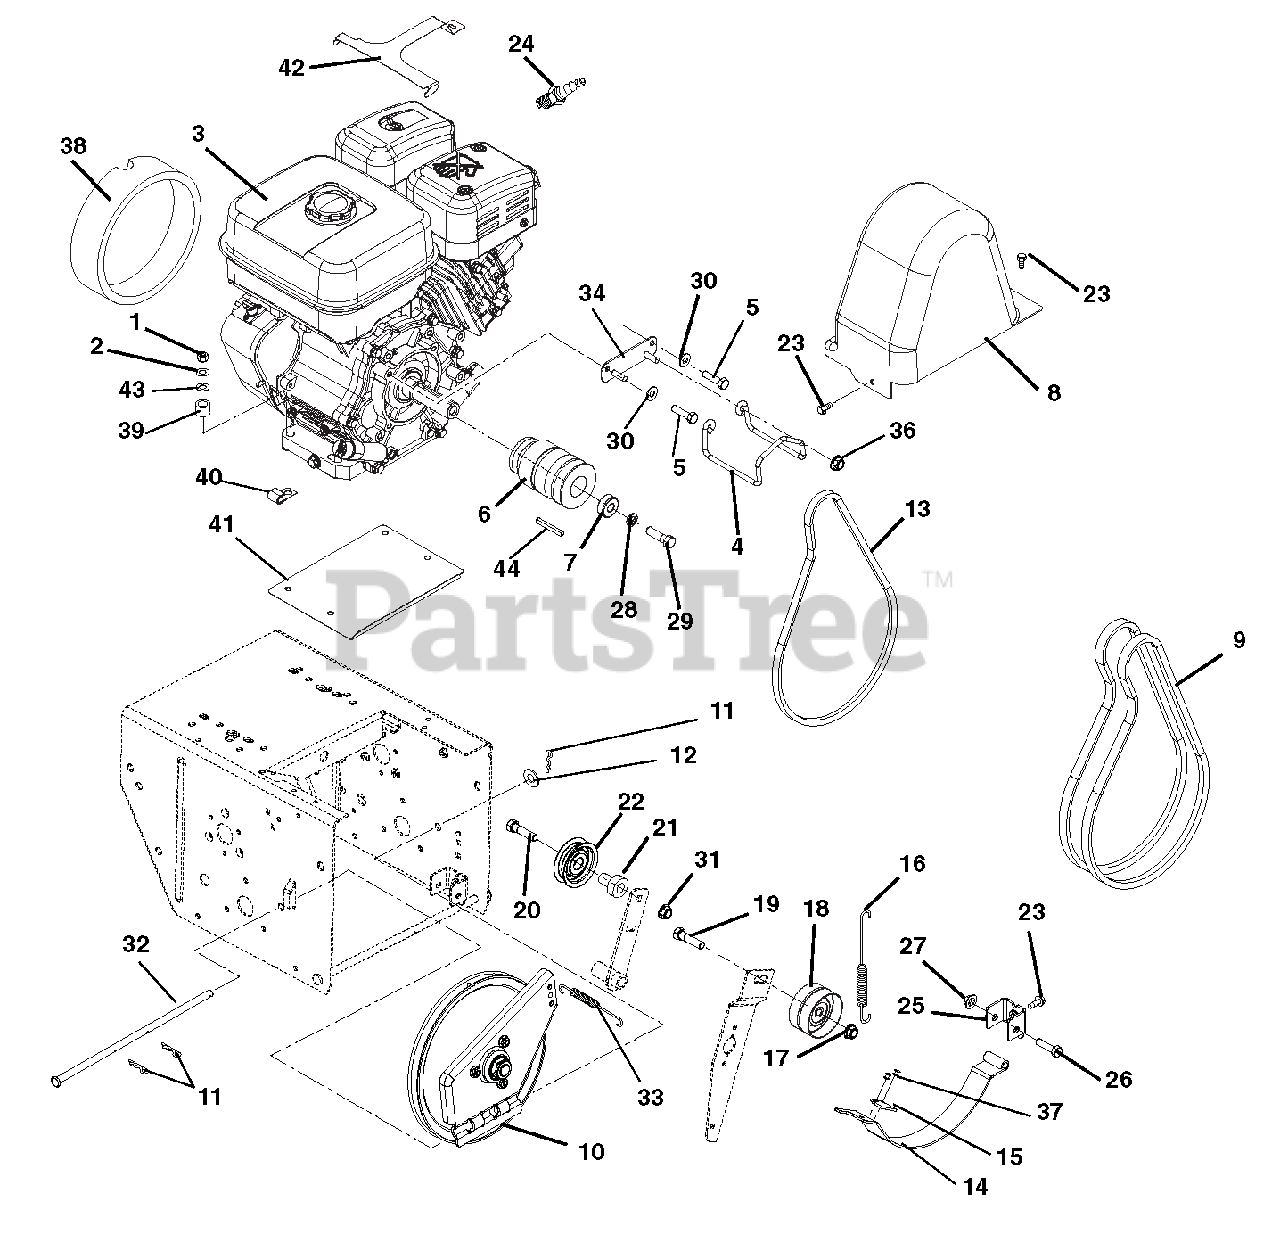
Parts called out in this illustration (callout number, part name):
1	@NUT-HEX .31-18 YWZC
2	WSHR-LK .312X.097 HVY YWZC
3	ENGINE,SUBARU EX27 AS RECOIL
4	FINGER, BELT
5	BLT-HEX .31-24X.75 YWZC GR5
6	SHEAVE, SUBARU EX27
7	BSHG-SPACER .47X1.25X.50
8	COVER, BELT-TALL PRO
9	V-BELT, HA-RAW EDGE (SET)
10	PLATE, SWING ASSEMBLY-DEEP
11	PIN-HAIR, ENDRIES #25 YWZC
12	@WSHR-FL-STL.406X.812X.065 YWZ
13	V-BELT, 3L-RAW EDGE
14	ARM, BRAKE-ATTACHMENT
15	PAD, BRAKE
16	SG-TENS .056X.60X4.40
17	@NUT-LK-TOP-FLG .38-16 YWZC
18	IDLER, FLAT 2.75" DIA
19	@BLT-HEX .38-16X1.50 GR5 YWZC
20	@BLT-HEX .31-18X1.25 GR5 YWZC
21	SPCR, BRG .315X.50X.688X.281
22	IDLER
23	SCR-TAP .25-20X.50 HWH TR YWZ
24	PLUG, SPARK
25	PIVOT, BRAKE
26	@BLT-HEX .31-18X2.00 GR5 YWZC
27	@NUT-LK-TOP-FLG .31-18 YWZC
28	@WSHR-LK .44X.109 REG YWZC
29	BLT-HEX .44-20X1.50 G5 YZ EP80
30	WSHR-LK .312X.097 HVY YWZC
31	@NUT-LK-TOP-FLG .31-18 YWZC
32	PIN, PIVOT
33	SG-TENS .048X.50X2.8
34	PLATE, BELT FINGER MOUNT
35	WSHR-FL-STL .536X1.07X.109 YZ
36	@NUT-LK-TOP-FLG .31-18 YWZC
37	RVT-POP .187 YZ
38	FOAM COVER, RECOIL-SUBARU
39	BSHG-SLV .325X.400X.795
40	J-CLAMP
41	BAFFLE, WATER-PRO SERIES
42	GUARD, SNOW-SUBARU
43	@WSHR-FL-STL.38X.875X.083 YWZC
44	KEY .25X.25X2.25
